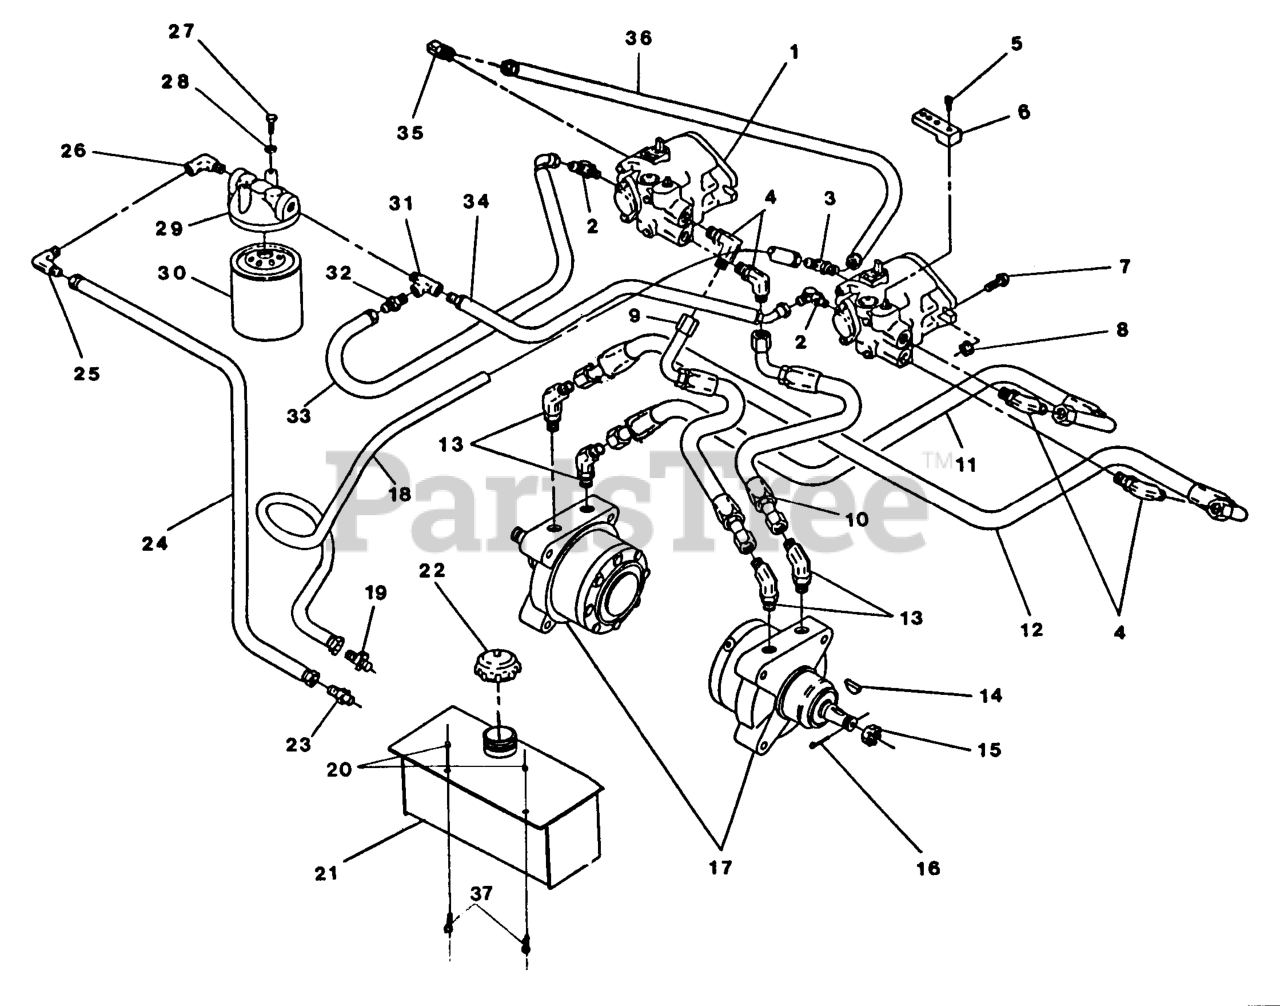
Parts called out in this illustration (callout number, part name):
2	ELBOW,90 DEGREE
9	HOSE,RH UPR LH FWD
13	FITTING,45 DEGREE
16	PIN-COTTER
23	FITTING-STRAIGHT
28	WASHER-LOCK
29	FILTER-HEAD
32	CONNECTOR,MALE
